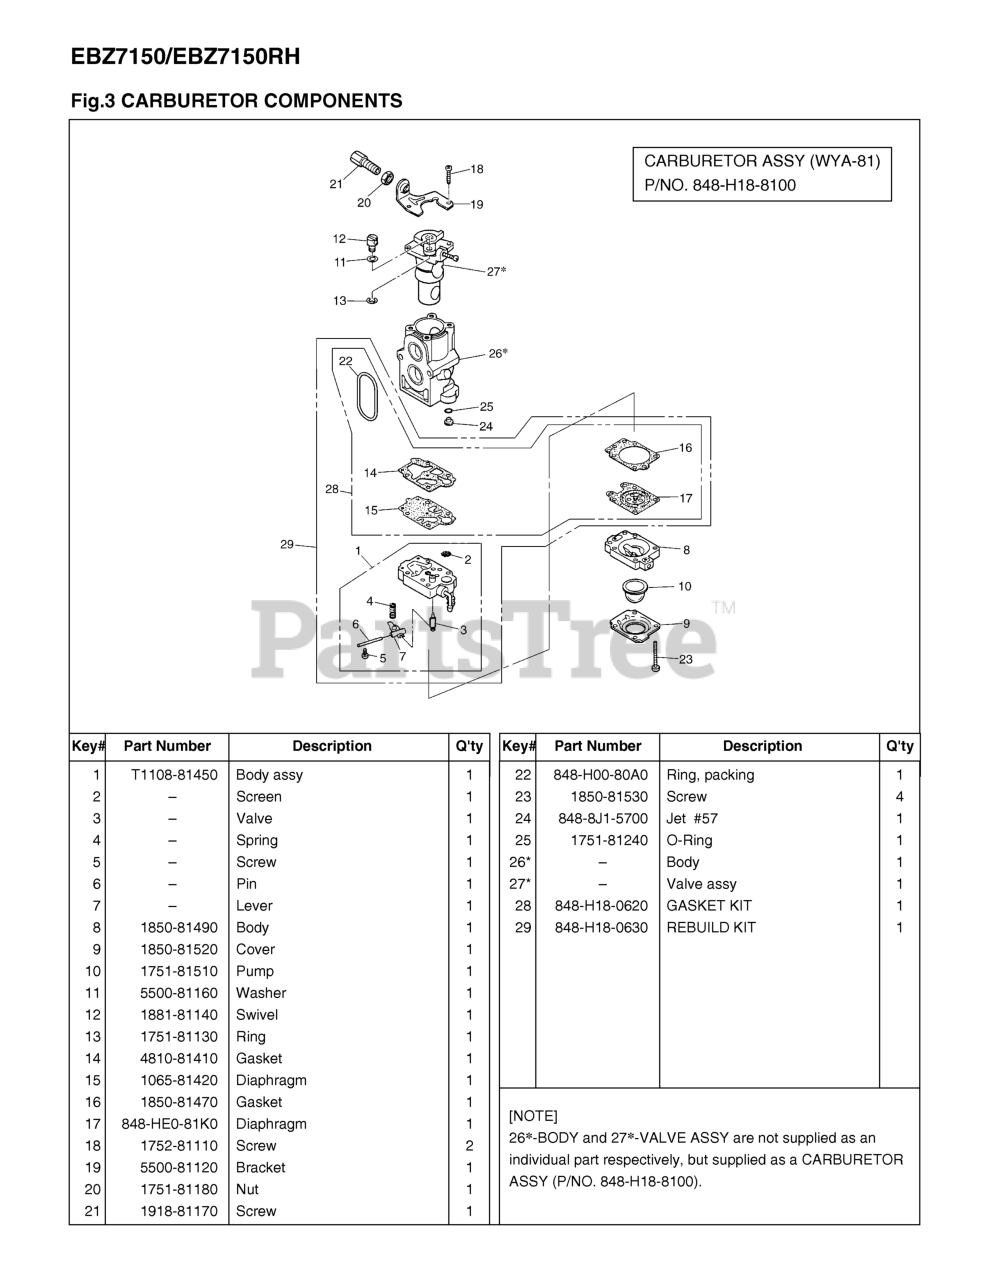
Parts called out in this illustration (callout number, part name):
1	BODY ASSY.
2	SCREEN
3	VALVE
4	SPRING
5	SCREW
6	PIN
7	LEVER
8	BODY, PURGE
9	COVER, PUMP
10	PUMP, PRIMING
11	WASHER
12	SWIVEL
13	RING
14	GASKET, PUMP
15	DIAPHRAGM
16	GASKET, DIAPHRAGM
17	DIAPHRAGM
18	SCREW
21	USE T160013170
22	RING, PACKING
23	SCREW
24	JET No.57
25	RING, O
26	CARBURETOR ASSY
27	CARBURETOR ASSY
28	GASKET KIT
29	REBUILD KIT
